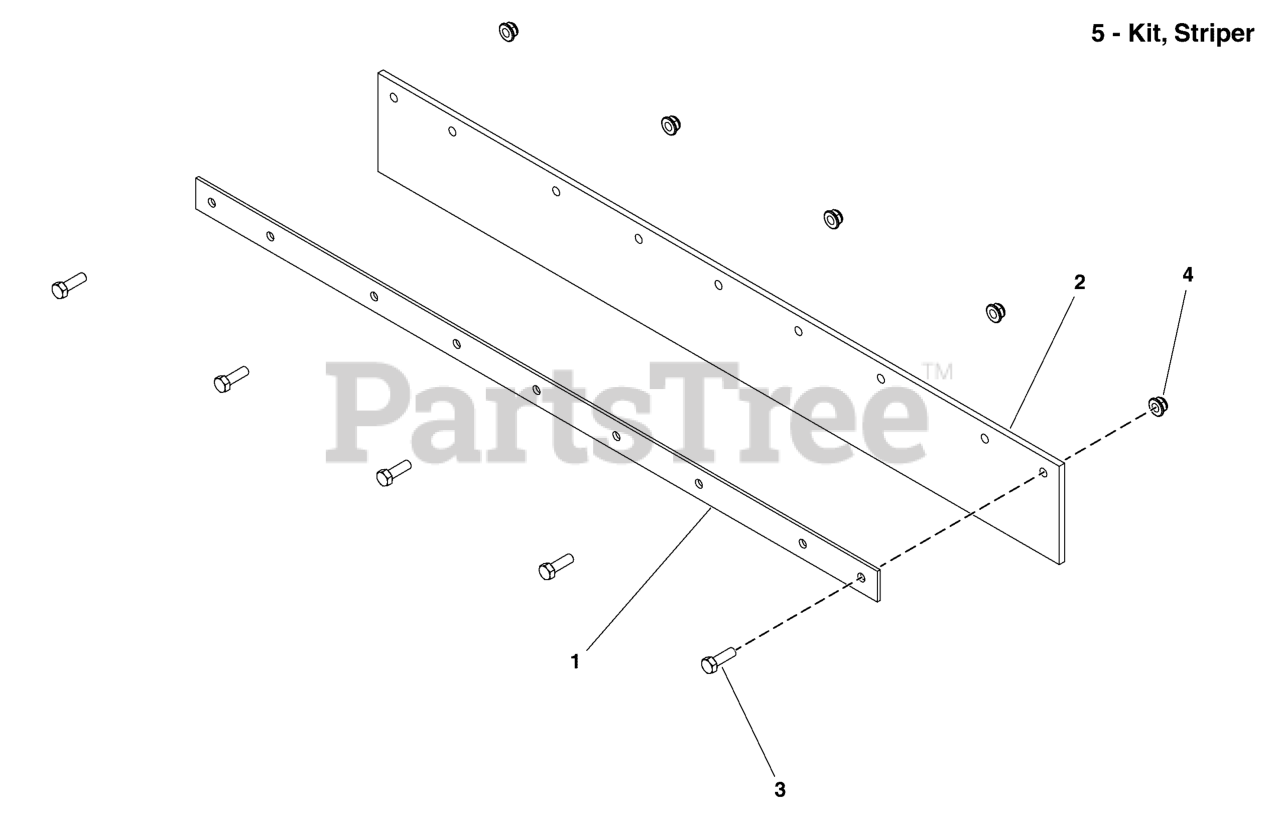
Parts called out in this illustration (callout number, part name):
1	PLATE SUPPORT IS1500 - BLK
2	FLAP STRIPER IS1500
3	BOLT, 5/16-18 X 1" GRD5 YZ
4	NUT, 5/16-18 HEX NYLOCK FLANGE NUT
5	KIT STRIPER CCW
